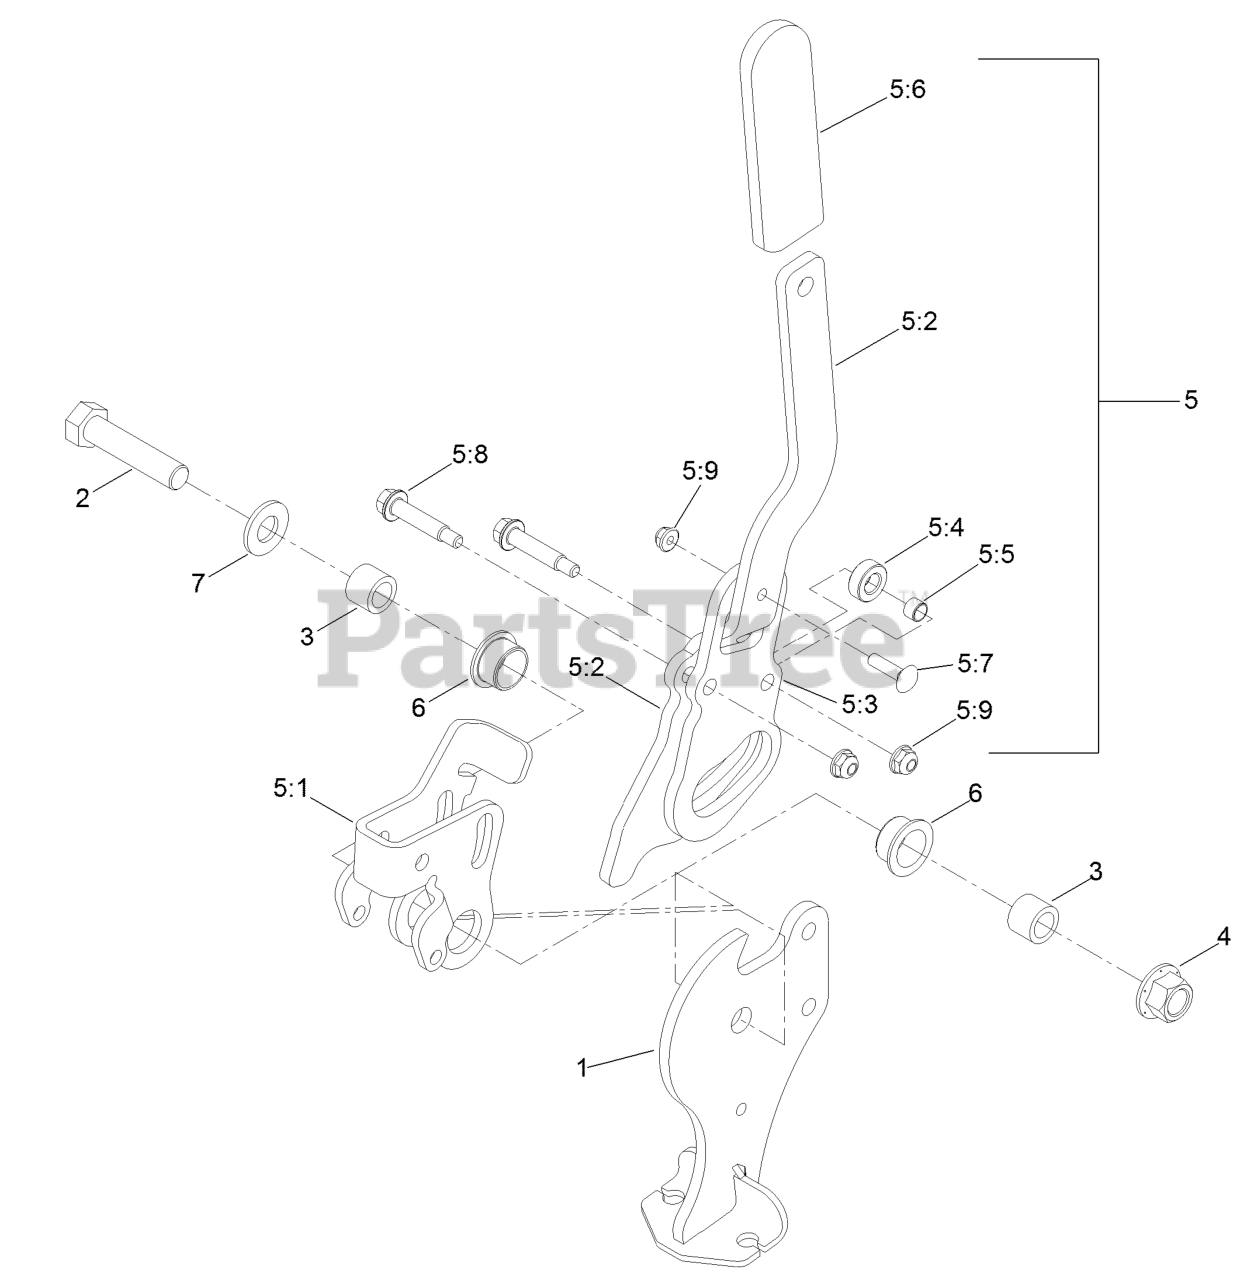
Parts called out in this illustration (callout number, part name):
1	PIVOT-BRAKE
2	SCREW-HH
4	Nut-Lock 1/2-13
5	HANDLE ASM
5:1	BELLCRANK-BRAKE
5:2	HANDLE-BRAKE
5:3	PLATE-HANDLE
5:4	ROLLER-BRAKE
5:5	BEARING-SLEEVE
5:6	GRIP-LEVER
5:7	SCREW-CARR
5:8	SCREW-SHOULDER
6	BUSHING-FLANGE
7	WASHER-FLAT
